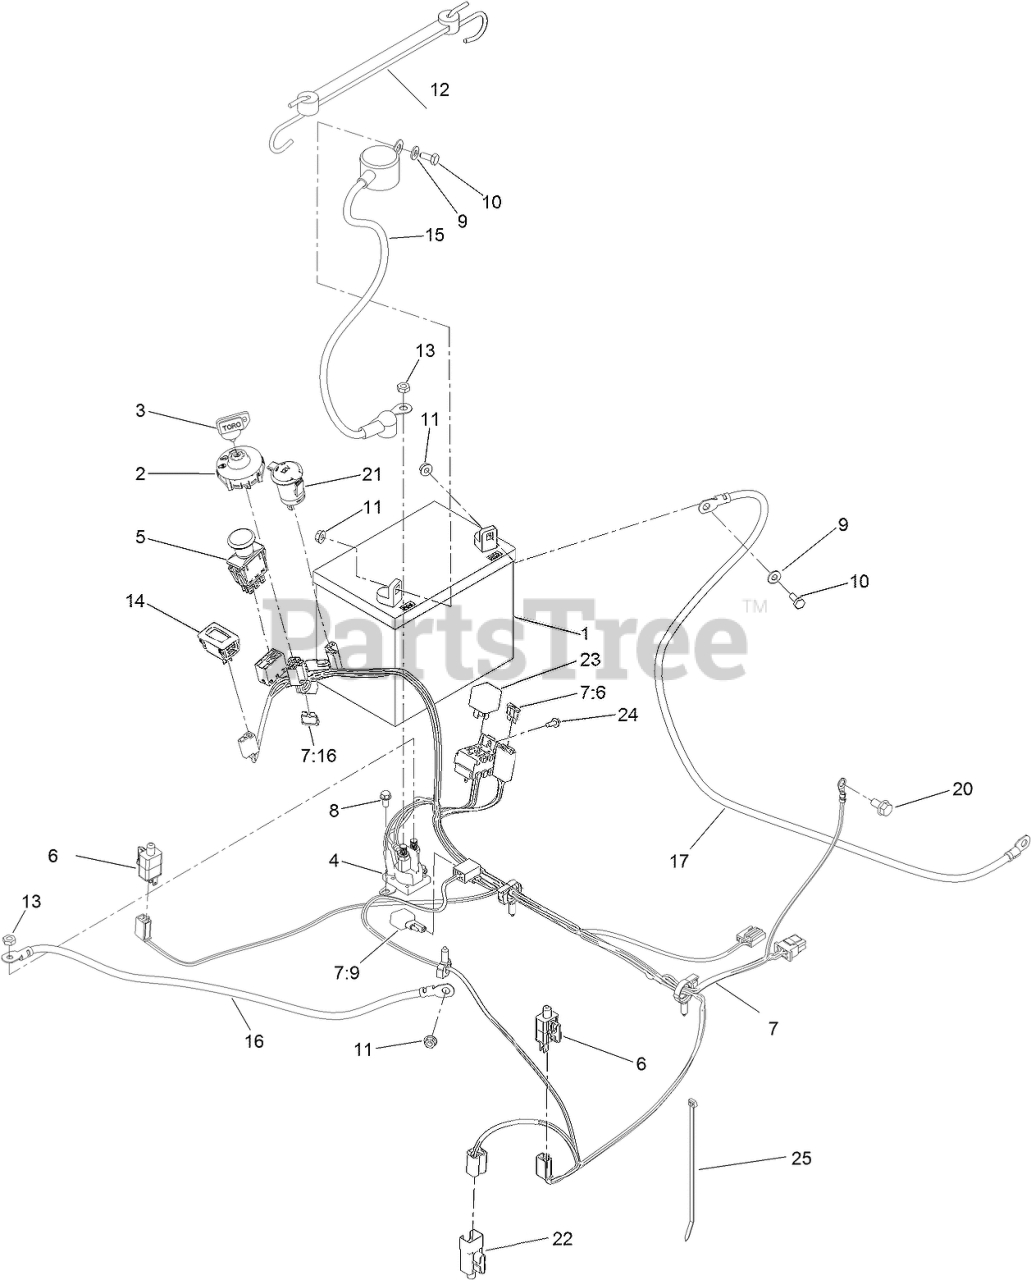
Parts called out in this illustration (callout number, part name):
1	BATTERY
2	SWITCH-IGNITION
3	KEY-IGNITION
4	SOLENOID
5	SWITCH-PTO
6	SWITCH
7	HARNESS-WIRING
7:6	FUSE-BLADE, 25 AMP
7:16	FUSE-BLADE, 15 AMP
8	SCREW-HWH
9	WASHER-FLAT
10	SCREW-HH
11	NUT-HF
12	HOLDDOWN-BATTERY
13	NUT-JAM
14	HOURMETER
15	CABLE-BATTERY, POSITIVE
16	CABLE-BATTERY, POSITIVE
17	CABLE-BATTERY, NEGATIVE
20	SCREW-HHF
21	PORT-POWER, 12V
22	SWITCH-REVERSE
23	RELAY
24	SCREW-TAPTITE
25	TIE-CABLE
